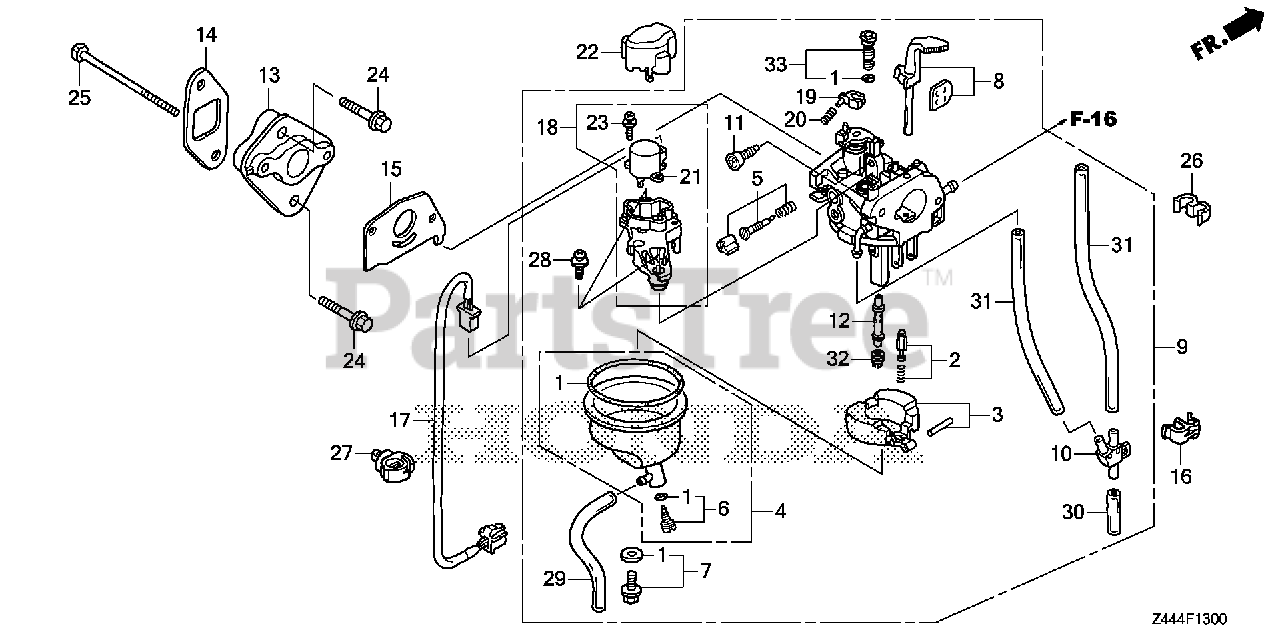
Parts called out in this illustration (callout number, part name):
1	GASKET SET (CARBURETOR NO.)
2	VALVE SET, FLOAT (CARBURETOR NO.) (SEAT NOT INCLUDED)
4	CHAMBER SET, FLOAT (CARBURETOR NO.)
5	SCREW SET (Honda Code 4219879). (CARBURETOR NO.)
6	SCREW SET, DRAIN (CARBURETOR NO.)
7	SCREW SET (CARBURETOR NO.)
9	CARBURETOR ASSY. (BF30H A)
10	JOINT, AIR VENT TUBE (CARBURETOR NO.)
11	SCREW, THROTTLE STOP
12	NOZZLE, MAIN
13	INSULATOR, CARBURETOR
14	GASKET, INSULATOR
15	GASKET, CARBURETOR
16	CLAMP, TUBE (7.5X2)
17	SUB-WIRE ASSY.
18	MOTOR ASSY., THROTTLE CONTROL
19	LEVER, LINK (CARBURETOR NO.)
20	SPRING, COMPRESSION COIL (CARBURETOR NO.)
21	MOTOR, THROTTLE CONTROL (CARBURETOR NO.)
22	COVER, THROTTLE MOTOR
23	SCREW-WASHER (3X8)
24	BOLT, FLANGE (6X25) (NSHF)
25	BOLT, HEX. (5X95)
26	CLAMP, TUBE (7X8)
27	CLIP, WIRE HARNESS (25MM)
28	SCREW-WASHER (4X10)
29	BULK HOSE, VINYL (3.5X6.5X8000) (9500(95003-05001-60M) (CARBURETOR NO.)
30	BULK HOSE, VINYL (4X7X8000) (95003-07(95003-07001-60M) (CARBURETOR NO.)
31	BULK HOSE, VINYL (4X7X8000) (95003-07(95003-07001-60M) (CARBURETOR NO.)
32	JET, MAIN (#60)
32	JET, MAIN (#62) (CARBURETOR NO.)
32	JET, MAIN (#65) (CARBURETOR NO.)
33	JET SET, PILOT (#38)
